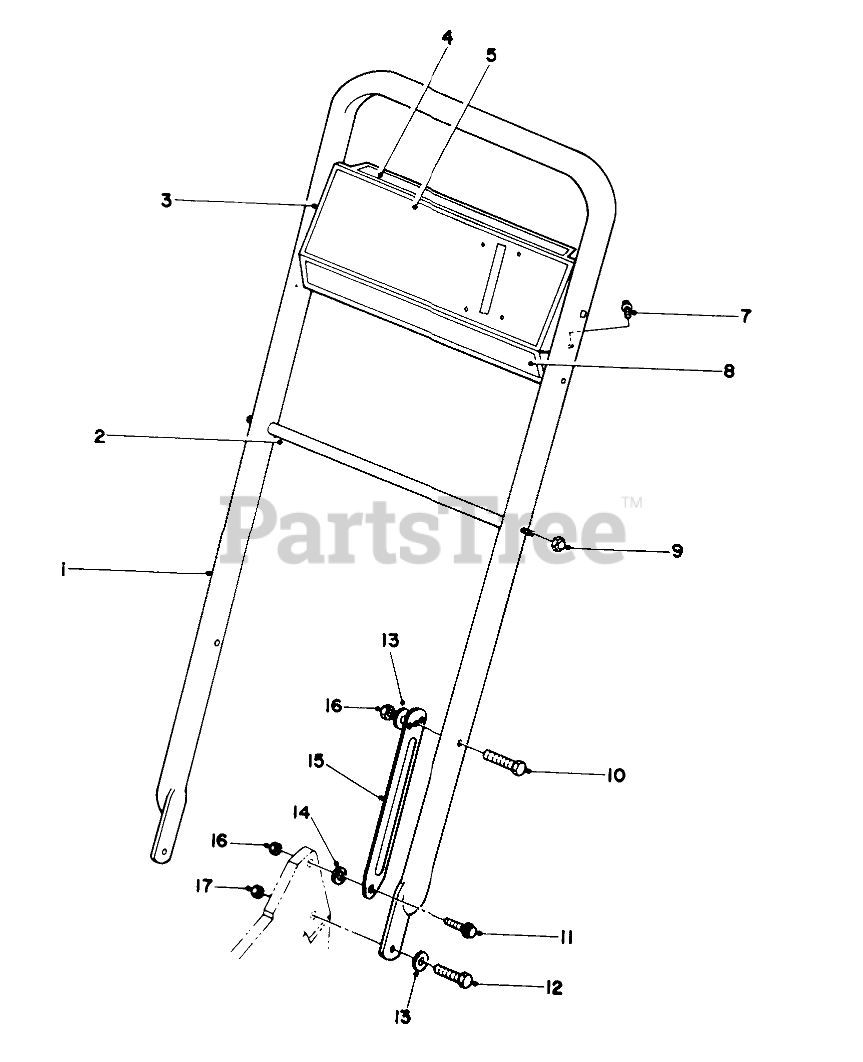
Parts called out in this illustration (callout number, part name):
1	Handle
2	ROD-SUPPORT, BAG
3	Panel-Control (Incl. Ref. #4, 5, & 8)
4	DECAL-PANEL, DANGER
5	DECAL-CONTROL PANEL
7	SCREW-HWHTF
8	DECAL-PANEL, PROLINE
9	NUT-CAP
10	SCREW-HH
11	SCREW-SHOULDER
12	SCREW-HH
13	WASHER-BELLEVILLE
14	SPACER
15	Latch-Handle
16	NUT-LOCK, NI
17	NUT-LOCK, NI
